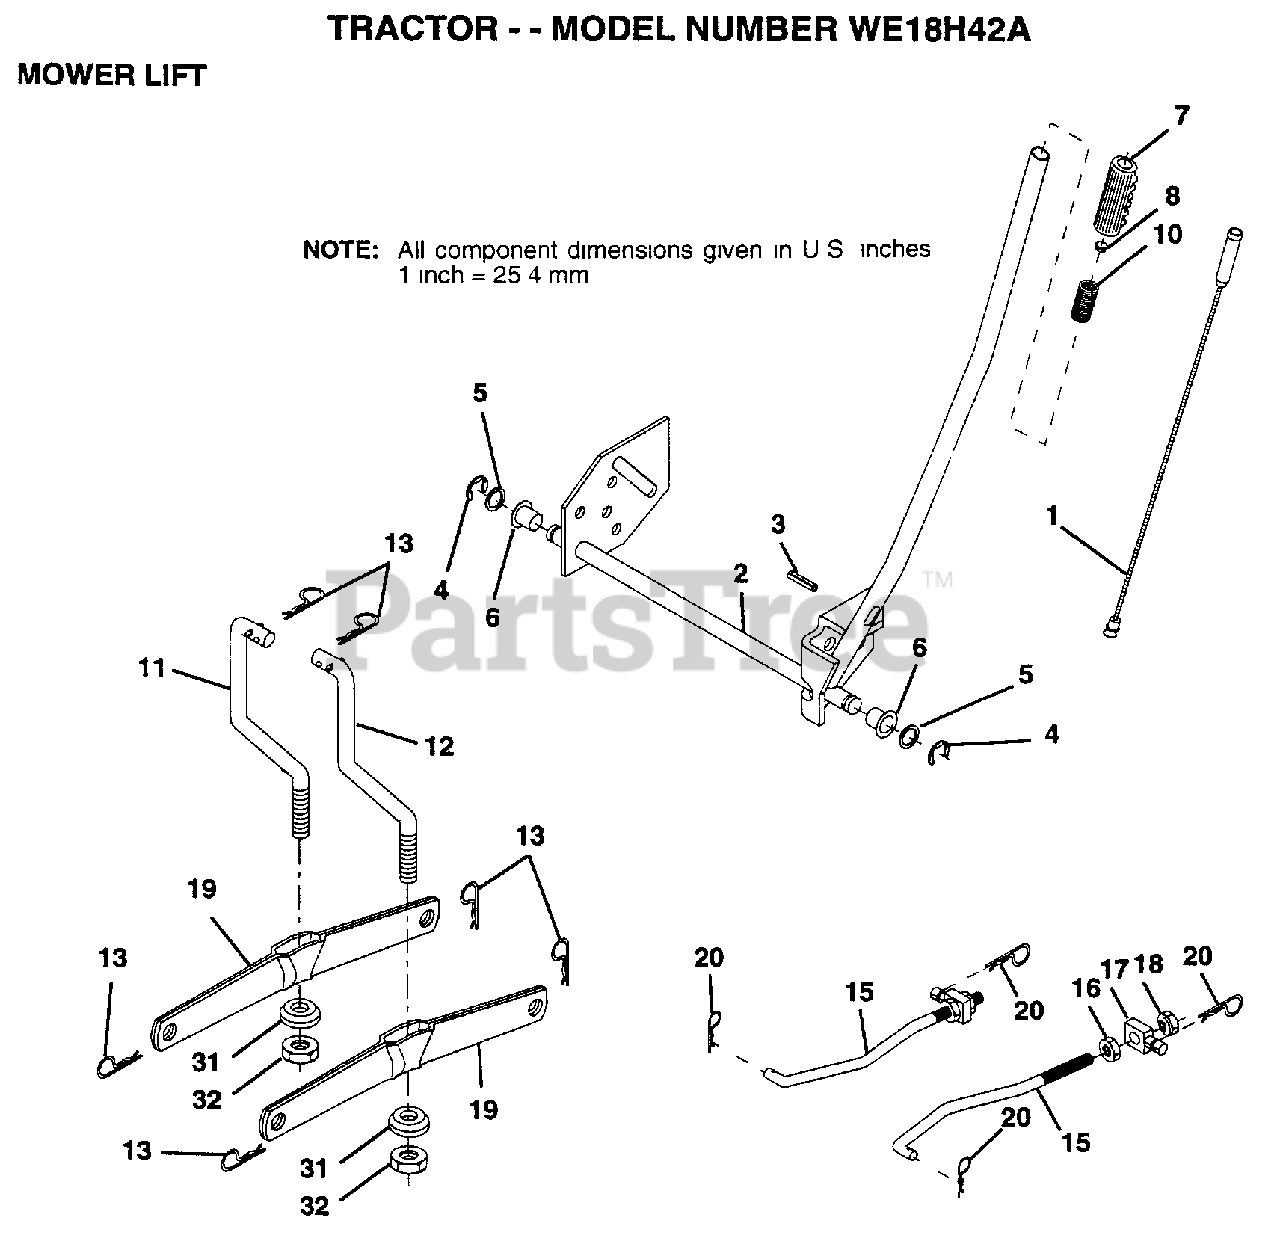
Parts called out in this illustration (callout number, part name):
1	WIRE.ASM.INNER
2	SHAFT.ASM.LIFT.RH
3	PIN GROOVE
5	WASHER
6	NYLON BEARING
7	GRIP
15	LINK.FRONT
16	NUT
17	TRUNION
18	NUT.LK.W/WSH.1/2.
19	ARM SUSP REAR
20	RETAINER.SPRING
31	BEARING PVT LH
32	NUT.CROWNLOCK.3/8
